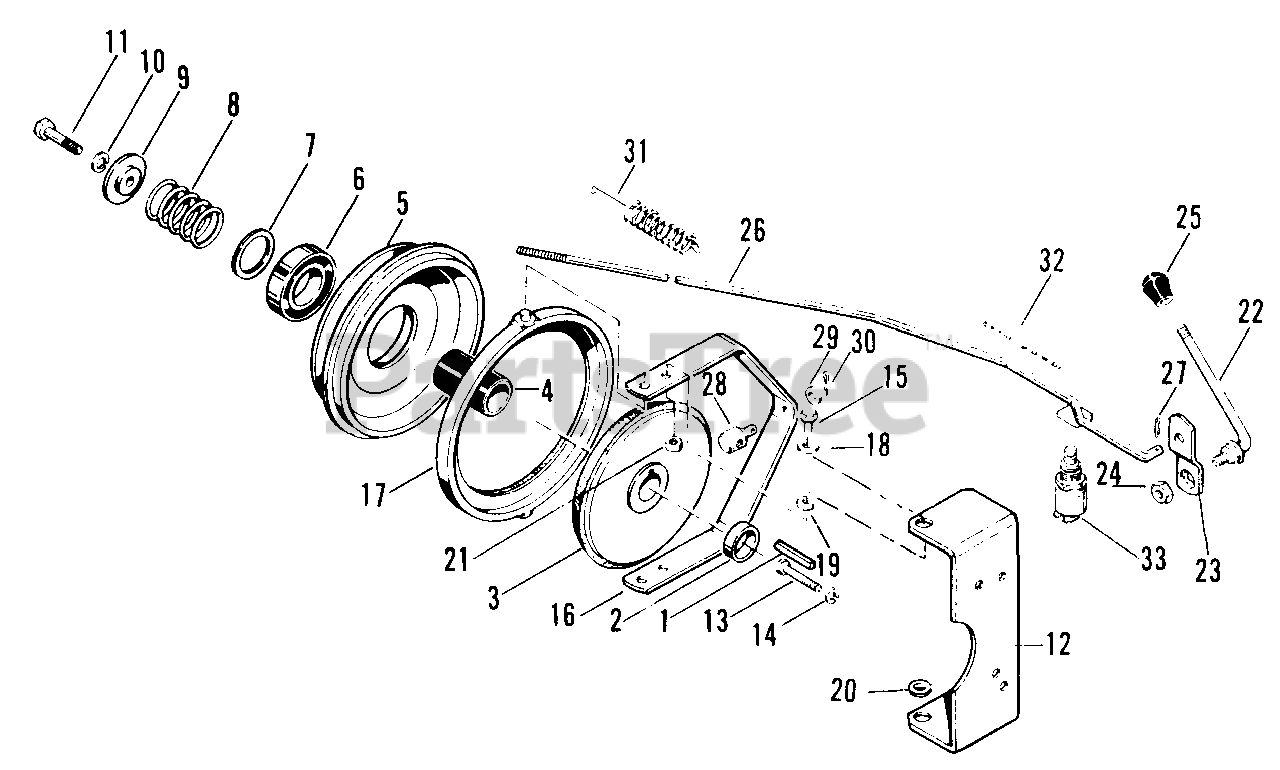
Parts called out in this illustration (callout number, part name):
1	KEY, Hi-Pro
3	Clutch Plate Assembly
6	Ball Bearing
9	Thrust Plate
10	Lock Washer, 3/8"
11	Hex Capscrew 3/8"-24 x 2"
13	Hex Capscrew, 5/16"-18 x 1"
14	Lock Washer, 5/16"
15	Hex Capscrew, 5/16"-18 x 3/4"
16	Clutch Fork
17	Brake Support Assembly
20	Plain Washer, 1/4"
21	Hex Nut, Full, Lock, 5/16"-18
22	Clutch Control Handle
23	P.T.O. Arm
24	Hex Nut, Full, Lock, 3/8"-16
25	Knob
26	Clutch Rod
27	Cotter Pin, 3/32" x 1/2"
29	Plain Washer, 1/4"
30	Cotter Pin, 3/32" x 1/2"
33	Safety Switch
